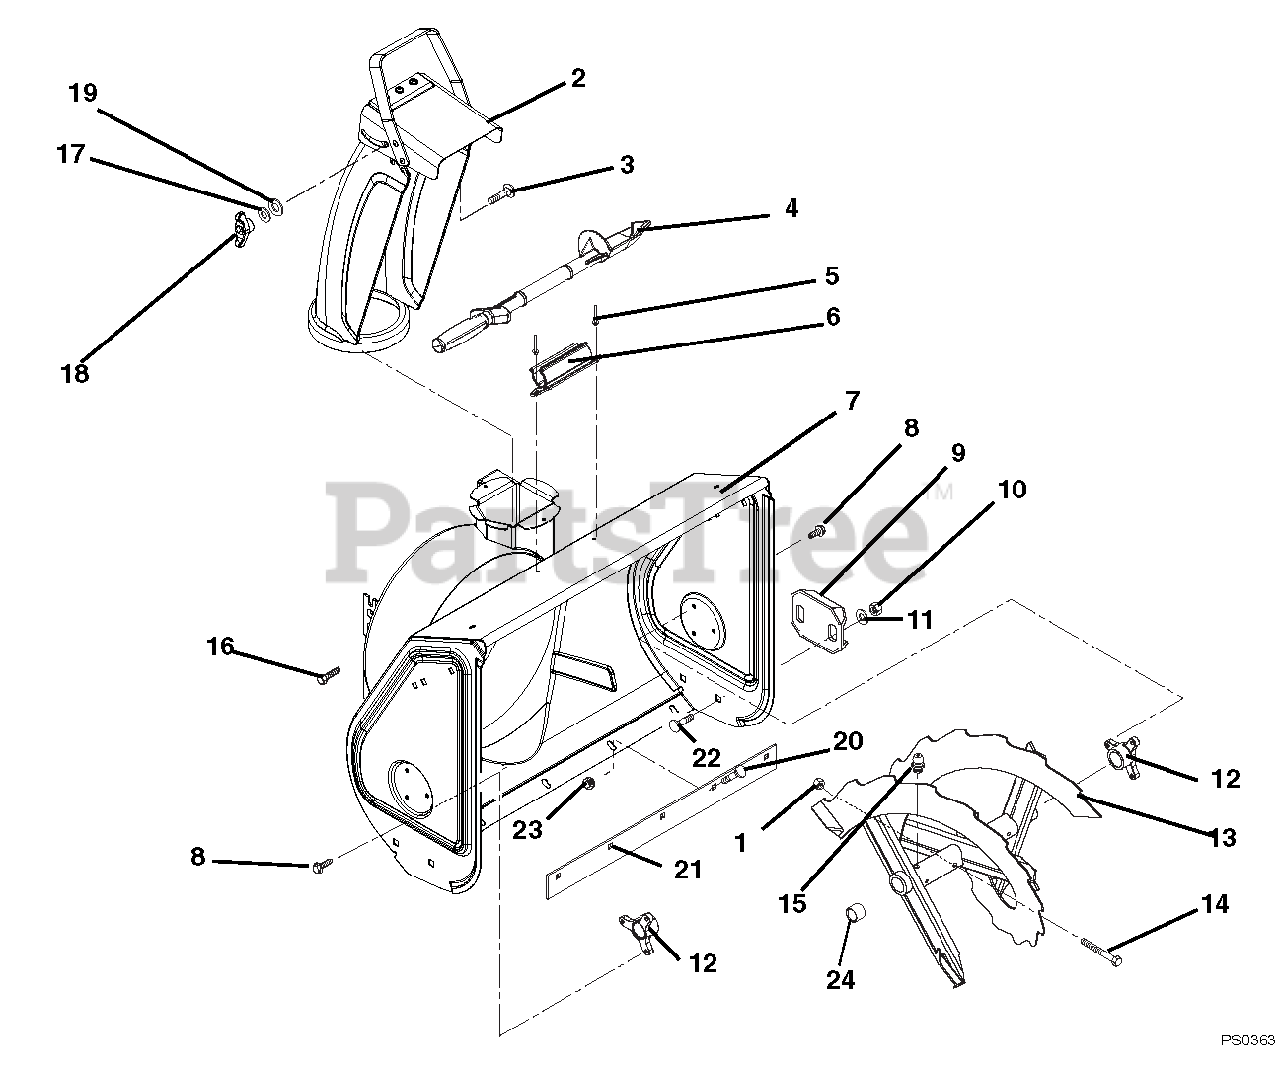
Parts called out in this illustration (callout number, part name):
1	@NUT-LK-CTR .25-20 YWZC
2	CHUTE, DISCHARGE W/CAP & DECAL
3	@BLT-RHDSSQNK .31-18X1.00 G5YZ
4	DEVICE, SNOW CLEAN OUT
5	RVT-POP .187 YZ
6	MOUNT, SNOW CLEAN OUT
7	BLOWER HOUSING W/DECAL 24" ST
7	BLOWER HOUSING W/DECAL 26" ST
8	SCR-TAP .25-20X.50 HWH TR YWZ
9	SKID SHOE, REVERSIBLE - BLACK
10	@NUT-LK-CTR .38-16 YWZC
11	@WSHR-FL-STL.38X.875X.083 YWZC
12	BUSHING, RAKE SHAFT .75"
13	RAKE, 24" RH, BLK SERR W/ZERK
13	RAKE, 24" LH, BLK SERR W/ZERK
14	SHEAR BOLT WITH NUT
15	ZERK,FITTING .25X.125 DRIVE IN
16	@SCR-TAP .31-18X.50 HWH TR YWZ
17	@WSHR-FL-STL.344X.688X.065YWZC
18	KNOB,WING .31-18 UNC NYL/TALC
19	WSHR-FL-NY .375X.75X.060
20	BLT,RDSHHDSQSHNK .31-18X.62 YZ
21	SCRAPER BLADE, 24" COMPACT HI
21	SCRAPER BLADE, 26" COMPACT HI
22	@BLT-RHDSSQNK .38-16X.75 G5YZ
23	@NUT-LK-TOP-FLG .31-18 YWZC
24	BSHG-SLV .75X1.12X1.062 NYL BK
